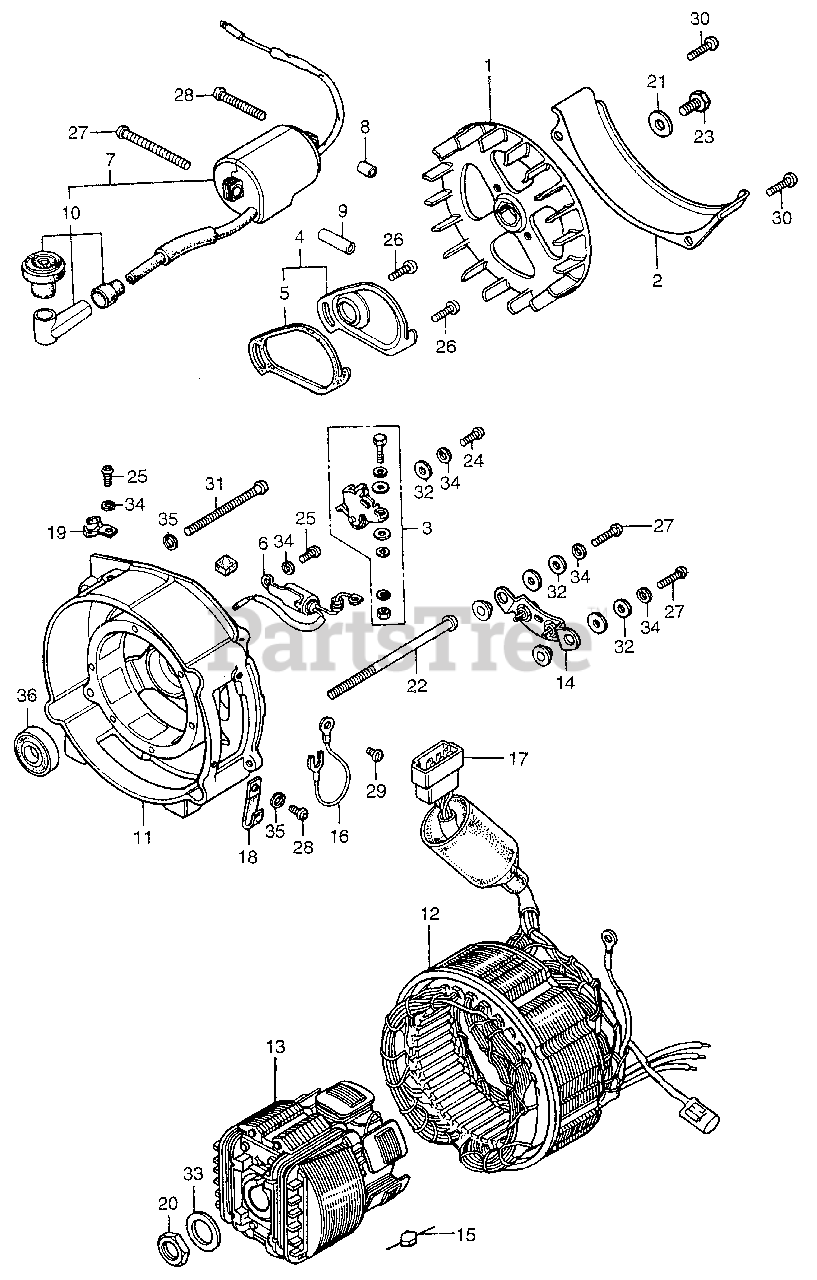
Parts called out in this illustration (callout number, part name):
1	FAN, ALTERNATOR COOLING (NOT AVAILABLE)
2	COVER, ALTERNATOR FAN
3	POINTS ASSY.
4	COVER ASSY., POINTS (NOT AVAILABLE)
5	GASKET, POINTS COVER (NOT AVAILABLE)
6	CONDENSER ASSY., IGNITION (NOT AVAILABLE)
7	COIL ASSY., IGNITION (NOT AVAILABLE)
8	COLLAR A, IGNITION DISTANCE (NOT AVAILABLE)
9	COLLAR B, IGNITION DISTANCE
10	TERMINAL ASSY., IGNITION (NOT AVAILABLE)
11	BRACKET, RR.
12	STATOR ASSY.
14	DIODE ASSY.
16	WIRE, GROUND
17	CONNECTOR, POLE (8)
18	CLAMP A, WIRE (NOT AVAILABLE)
19	CLAMP, WIRE
20	NUT, SPECIAL (14MM)
21	WASHER (6X17)
22	BOLT, ALTERNATOR SET (NOT AVAILABLE)
23	BOLT, HEX. (6X14)
24	SCREW, PAN (4X6)
25	SCREW, PAN (4X8)
26	SCREW, PAN (4X12)
27	SCREW, PAN (4X14)
28	SCREW, PAN (5X8)
29	SCREW, PAN (5X8)
30	SCREW, PAN (5X10)
31	SCREW, PAN (5X55) (NOT AVAILABLE)
32	WASHER, PLAIN (4MM)
33	WASHER, FLAT (14MM)
34	WASHER, SPRING (4MM)
35	WASHER, SPRING (5MM)
36	BEARING, RADIAL BALL (6001UU) (SOURCE: VINTAGE PARTS INC.)
